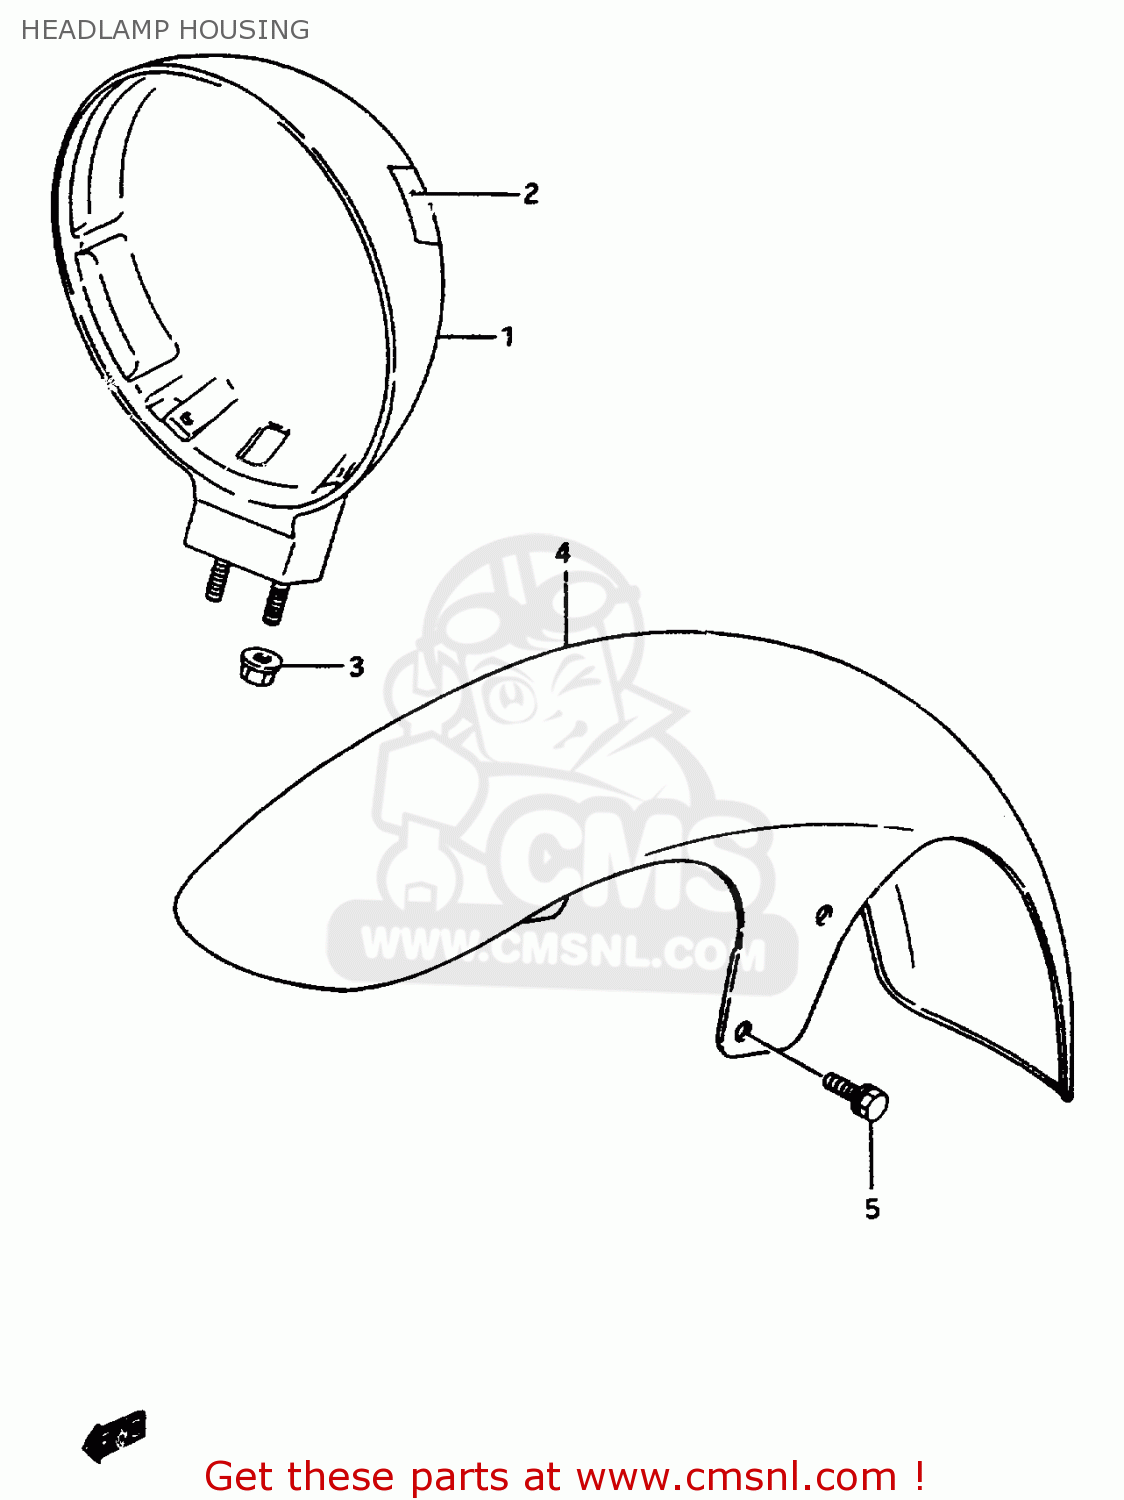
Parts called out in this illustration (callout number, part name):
1	HOUSING,HEADLAMP
2	TAPE,FRAME HEAD COVER
3	NUT
4	FENDER,FR
5	BOLT
